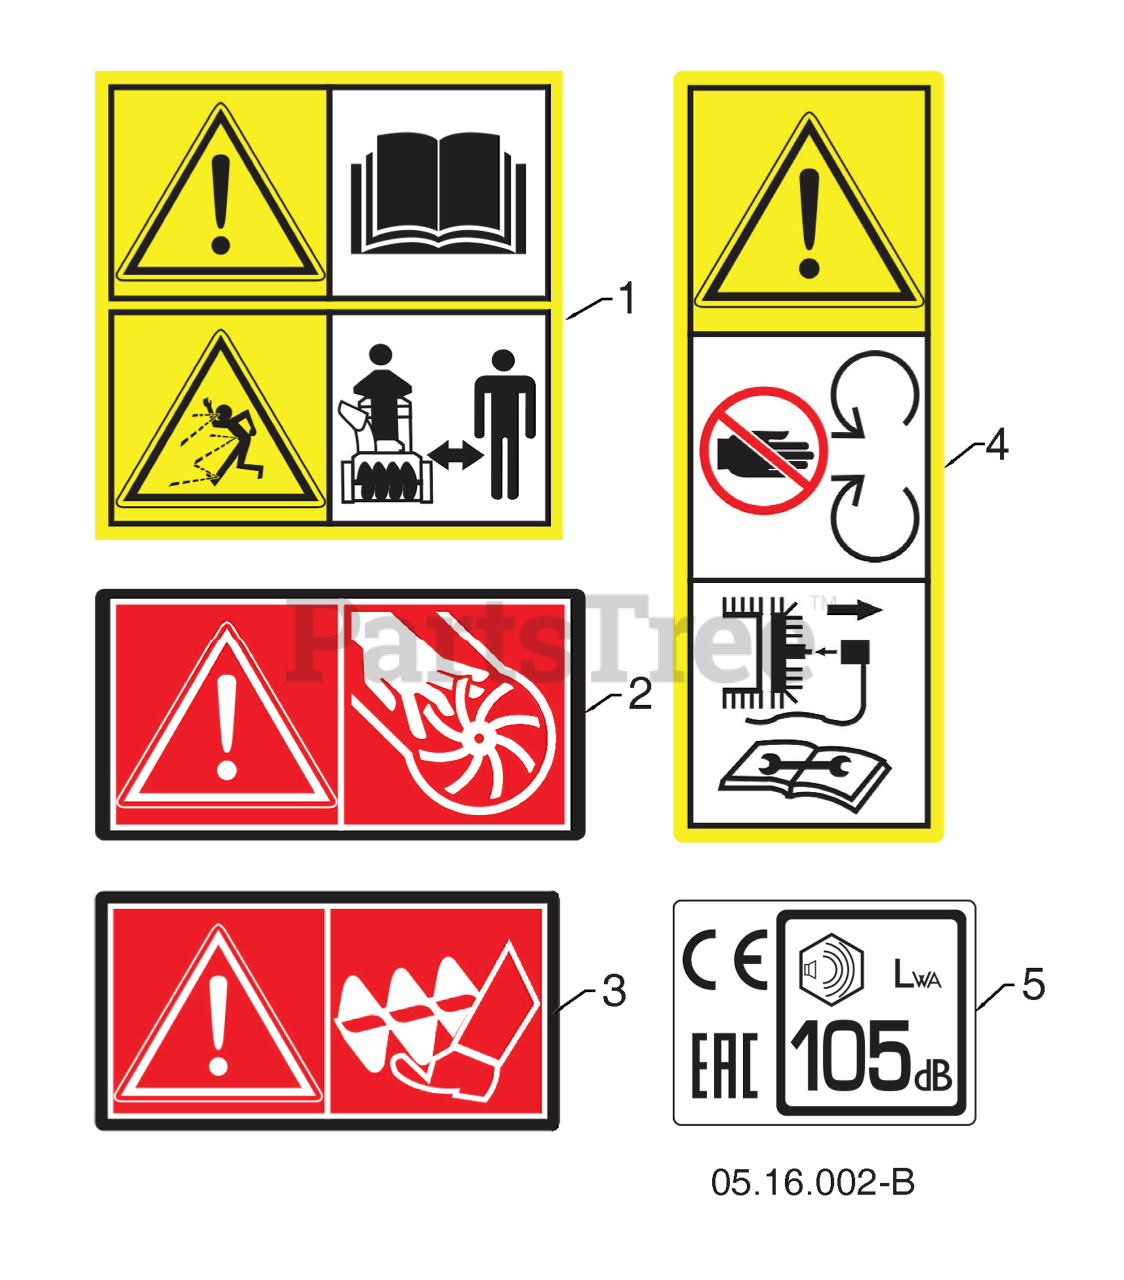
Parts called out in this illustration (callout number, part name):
1	DECAL.AUGER."
2	DECAL.CHUTE.SAFETY.EU/SC.17
3	DECAL.AUGER.SAFETY.
4	DECAL.BELT.GUARD.
5	DECAL.NOISE.LEV.105/CE.EAC.UKR
